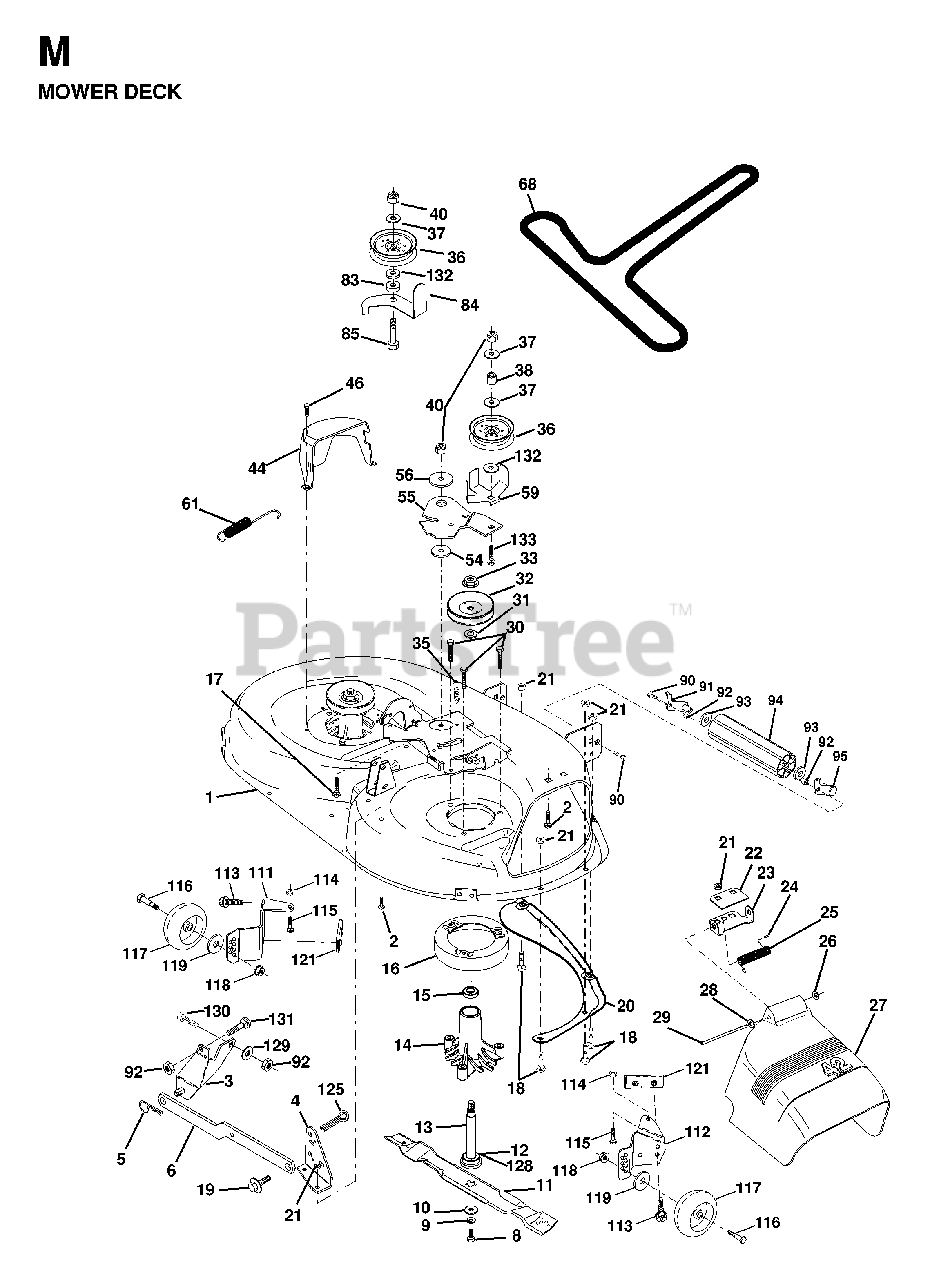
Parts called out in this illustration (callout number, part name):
1	DECK 42"
2	BOLT
3	BRKT ASM SWAY BAR
4	BRKT DECK SW BAR
5	RETAINER-SPRNG RB
6	REAR SUSP ARM
8	BLADE BOLT
9	LOCKWASHER
10	WASHER.BLADE
11	BLADE 42"
12	BEARING
13	SHAFT ASM VENT
14	HSG MANDREL
16	STRIPPER
17	BOLT CARRIAGE
18	BOLT
19	BOLT SHD 5/16-18
20	BAFFLE.VORTEX
21	LOCKNUT
22	STIFFENER BRACKET
23	DEFLECTOR BRACKET
24	CAP-SLEEVE LT
25	SPRING TORSION
26	NUT PUSH M
27	SHIELD.DEFLECTOR.MOWER.42".BLK
28	WASHER
29	ROD.HINGE
30	SCREW THDROL ROLLING WASHER HD
31	WASHER
32	PULLEY/MANDREL
33	NUT
35	FASTENER.XMAS.TREE
36	FLAT IDLER PULLEY
38	IDLER SPRING SPACER
40	LOCKNUT
44	GUARD MANDREL LH BLACK
46	SCREW.1/4-20X5/8
54	HARDENED WASHER
55	IDLER ARM
56	SPACER RETAINER
59	GUARD, BELT
61	SPRING EXTENSION
68	V-BELT TRIPATH
84	KEEPER.BELT.IDLER
85	BOLT
90	BOLT
91	BRACKET LH (A)
92	NUT
94	NOSE ROLLER
95	BRACKET RH (B)
111	BRACKET WHEEL GAUGE LH 42" DK
112	BRACKET WHEEL GAUGE RH 42" DK
113	SCREW
114	NUT
115	BOLT
118	LOCKNUT
119	WASHER
121	BRACKET.EXTRD.GWL
125	COTTER PIN
128	WASHER FELT
129	WASHER
131	BOLT D
132	WASHER GT
